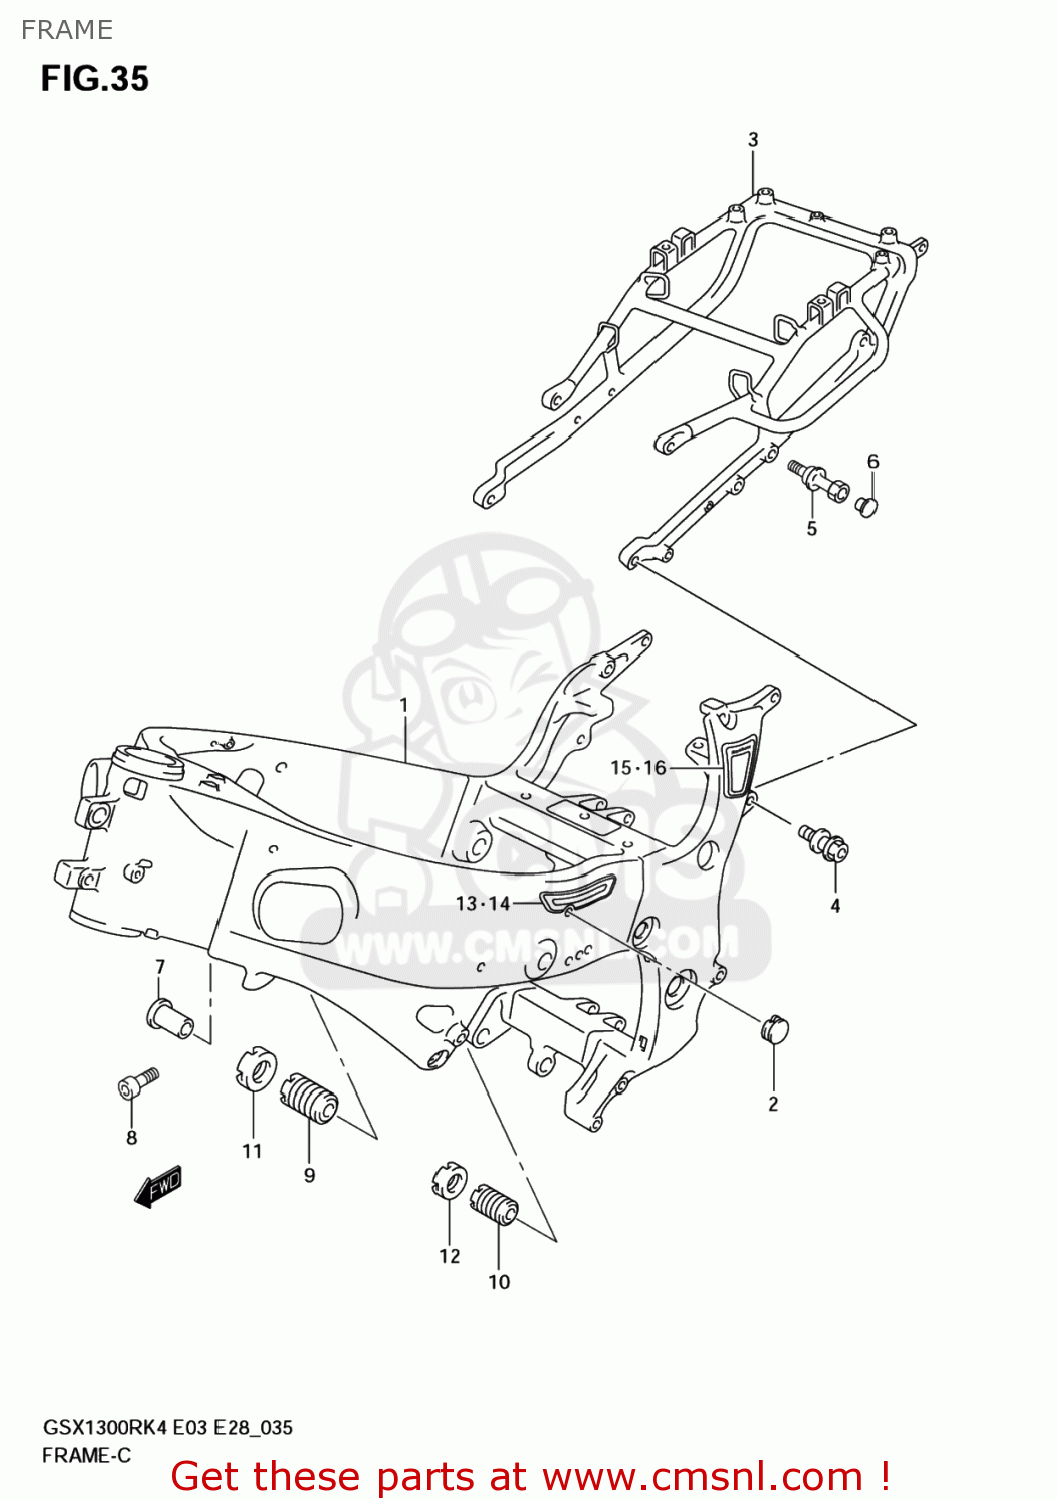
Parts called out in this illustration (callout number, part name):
1	FRAME (BLACK)
2	CAP,TANK RAIL
3	PAIL,SEAT
4	BOLT(10X30)
5	HOOK,SEAT RAIL
6	CAP(OD:10)
7	SPACER,ENGINE MTG
8	BOLT(8X30)
9	BOLT,CRANKCASE ADJUST
10	BOLT,CRANKCASE ADJUST
11	NUT,CRANK CASE ADJUST
12	NUT,CRANKCASE ADJUST
13	PAD,TANK RAIL,R
14	PAD,TANK RAIL,L
15	EMBLEM,FRAME BODY,R
16	EMBLEM,FRAME BODY,L
